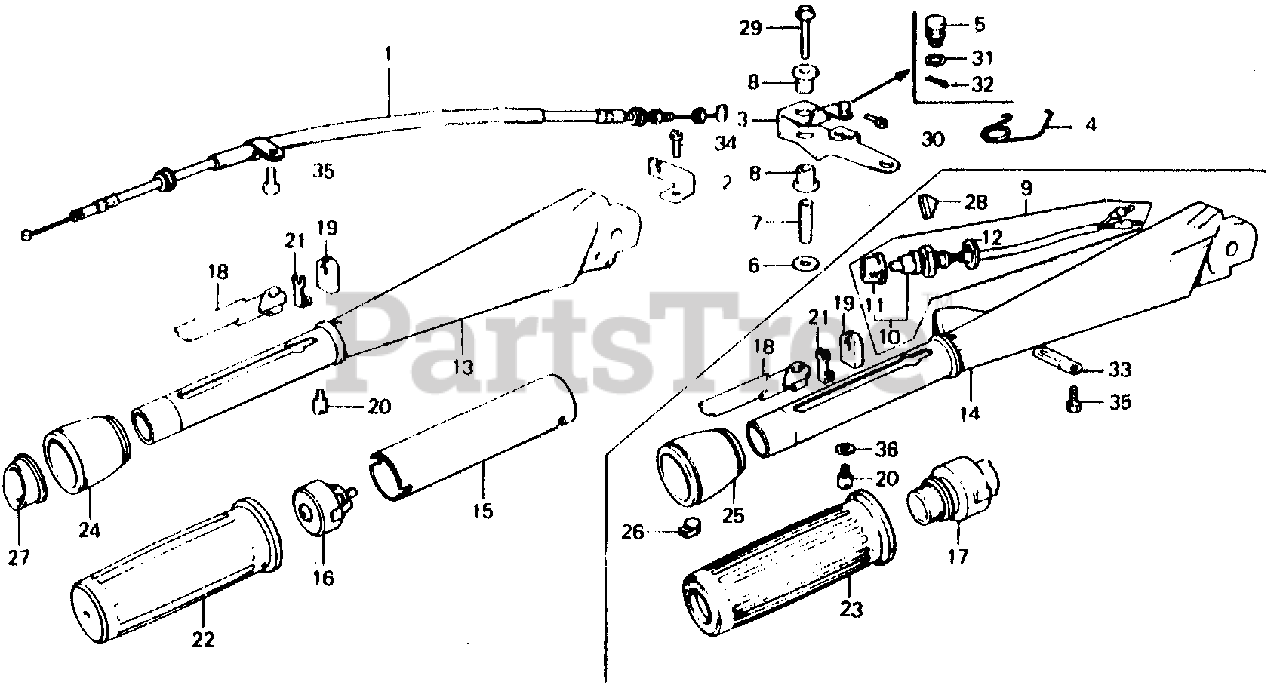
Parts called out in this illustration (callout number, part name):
1	CABLE, THROTTLE
2	HOLDER, CABLE
3	ARM, THROTTLE
4	SPRING, THROTTLE ARM
5	HOLDER, STARTER ROD
6	WASHER, PIVOT
7	COLLAR, PIVOT
8	BUSH, SHAFT
10	SWITCH ASSY., ENGINE STOP
11	CAP, BUTTON
14	HANDLEBAR *B9* (ATLANTIS BLUE)
15	PIPE, GRIP (NOT AVAILABLE)
17	NUT, GRIP FRICTION
18	HINGE, THROTTLE WIRE
19	HOLDER, THROTTLE CABLE
20	STOPPER, GRIP PIPE
21	STOPPER, CABLE
23	RUBBER, GRIP
25	COVER, GRIP PIPE
26	GROMMET, HANDLE COVER
28	MARK, HANDLE FOREIGN (NOT AVAILABLE)
29	BOLT, FLANGE (6X35) (NOT AVAILABLE)
30	BOLT, SLOTTED (4X6)
31	WASHER, PLAIN (6MM)
32	PIN, SPLIT (2.0)
33	CLIP B, CORD
34	BOLT, HEX. (6X12)
35	BOLT, HEX. (6X12)
36	WASHER, PLAIN (5MM)
